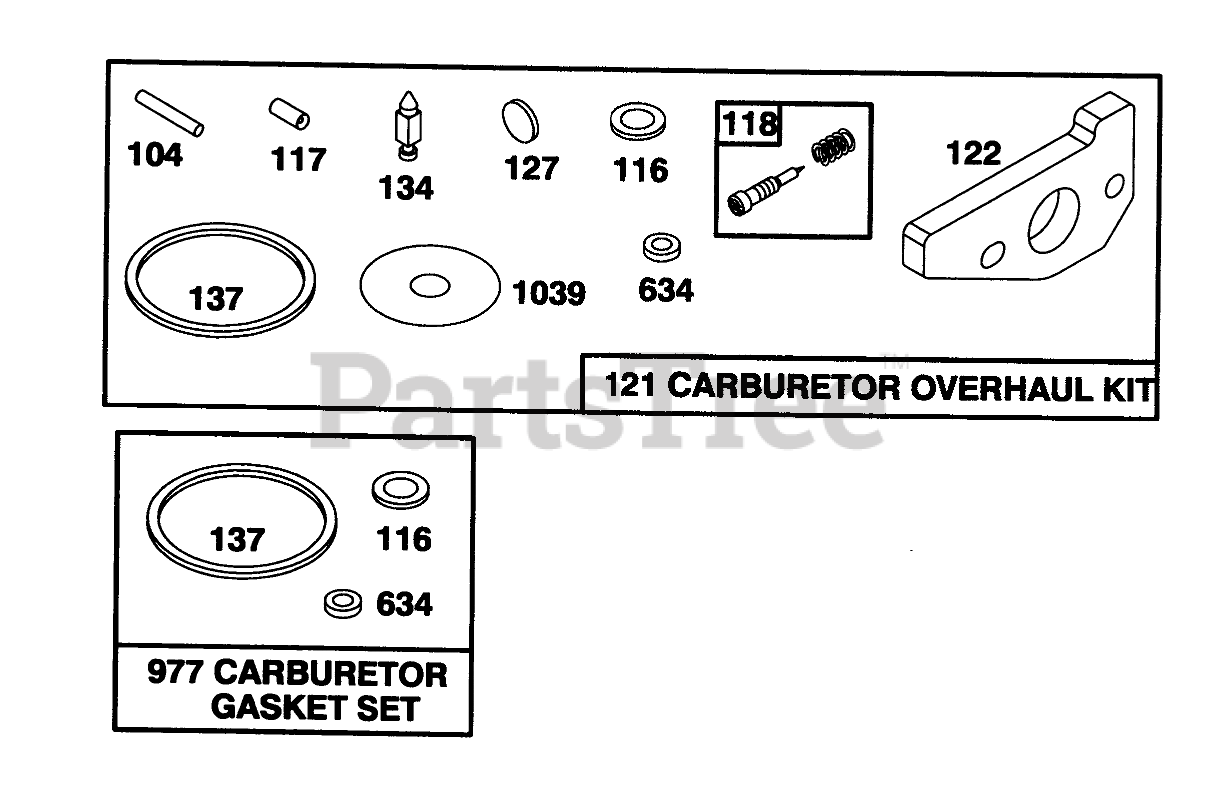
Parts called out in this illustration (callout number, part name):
104	FLOAT HINGE PIN
116	SEALING GASKET
118	VALVE KIT - NEEDLE
121	CARBURATOR OVERHAUL KIT
122	ADAPTER ASSEMBLY
134	Valve-Float (Includes Seat)
137	FLOAT BOWL GASKET
634	SEAL WASHER
977	CARBURATOR GASKET SET
1039	FLOAT LIMITER
